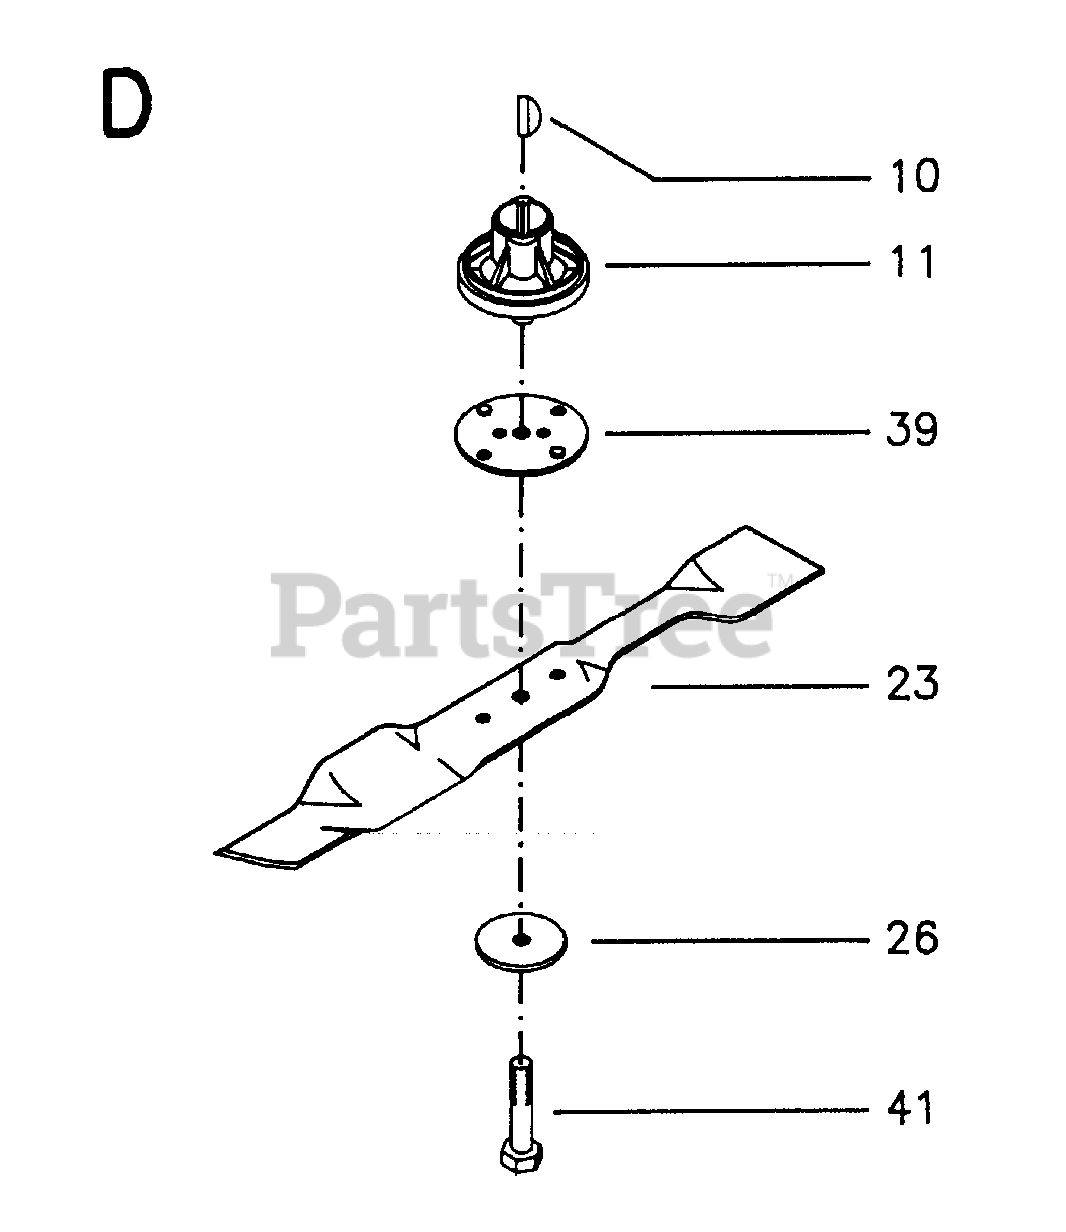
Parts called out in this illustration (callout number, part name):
11	BLADE ADAPTER
39	STEEL PLATE ADAPTER
41	REPL BY 515 12 39-31
